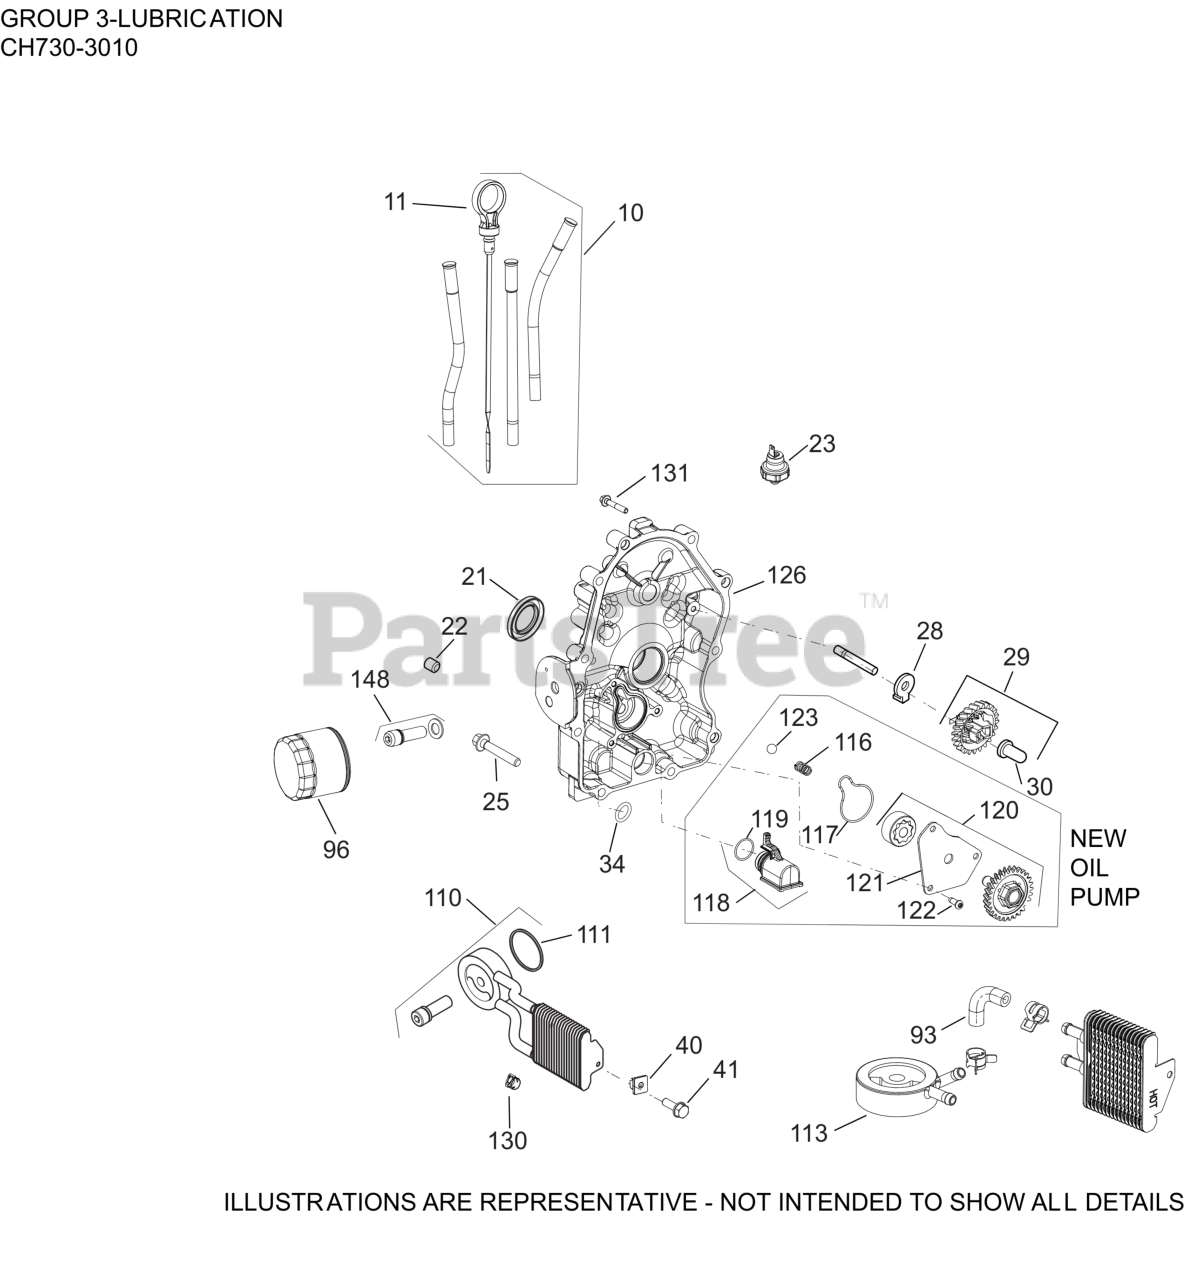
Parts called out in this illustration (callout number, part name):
10	KIT, DIPSTICK/DIPSTICK TUBES
22	PLUG, CTSK PIPE 1/8"
23	SENSOR, OIL PSI
25	SCREW, FLG M8X1.25X45
28	TAB, LOCKING
29	KIT, GOVERNOR GEAR W/PIN
30	PIN, GOVERNOR REGULATING
40	NUT, PLASTIC - BLACK
41	SCREW, HEX HEAD
93	KIT, HOSE 140MM
96	OIL FILTER
110	COOLER,OIL&DIVERTER ASSY-USE 24 594 69-S
111	O-RING, OIL COOLER
113	ADAPTER,OIL FILTER (CV EFI)-(#DSC)
116	SPRING, COMPRESSION
117	SEAL, OIL PUMP COVER
118	PICK-UP ASSEMBLY, OIL
119	O-RING, OIL PICK-UP
120	PUMP ASSEMBLY, OIL
121	COVER, OIL PUMP
122	SCREW, BUTTON HEAD
123	PRESSURE RELIEF BALL
126	KIT, CLOSURE PLATE ASSY
130	CLAMP, HOSE LOW PROFILE
131	SCREW, HEX FLANGE
148	KIT, OIL FILTER NIPPLE
NI	SHAFT, GOVERNOR GEAR
